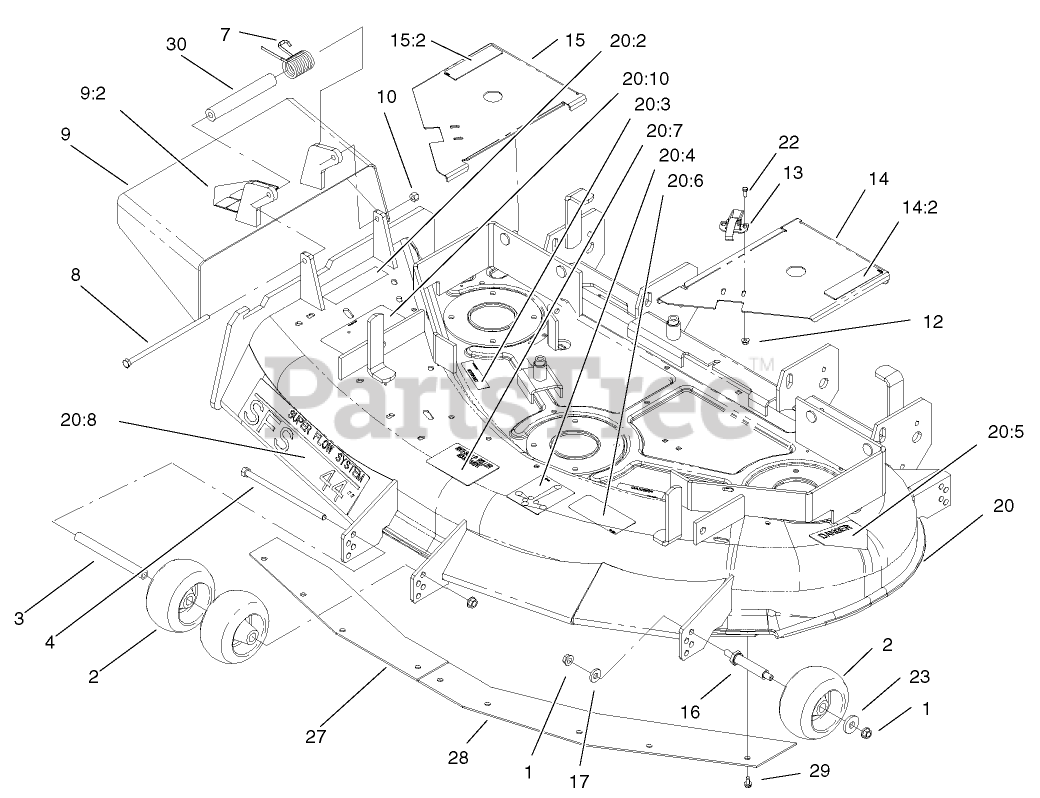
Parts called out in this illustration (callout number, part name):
1	NUT-HHF, WHIZ
2	WHEEL-GAGE
3	SPACER-WHEEL
4	SCREW-HH
7	SPRING-TORSION
8	SCREW-HH
9	Deflector ASM
9:2	DECAL-DANGER
10	NUT-LOCK, NI
12	NUT-LOCK, FLANGE
13	CLAMP-SLOTTED
14	LH COVER ASM
14:2	DECAL-DANGER
15	RH COVER ASM
15:2	DECAL-DANGER
16	SPACER
17	WASHER-BELLEVILLE
20	DECK DECAL ASM
20:2	DECAL-WARNING
20:3	DECAL-COVER, MISSING
20:4	DECAL-ROUTING, BELT
20:5	DECAL-DANGER
20:6	DECAL-TORQUE, BLADE BOLT
20:7	DECAL-WHEEL, GAGE
20:8	DECAL
20:10	DECAL-DANGER, THROWN OBJECT
22	SCREW-HWH
23	WASHER
27	PLATE-BLOWOUT, RH
28	PLATE-BLOWOUT, LH
29	SCREW
30	SPACER
